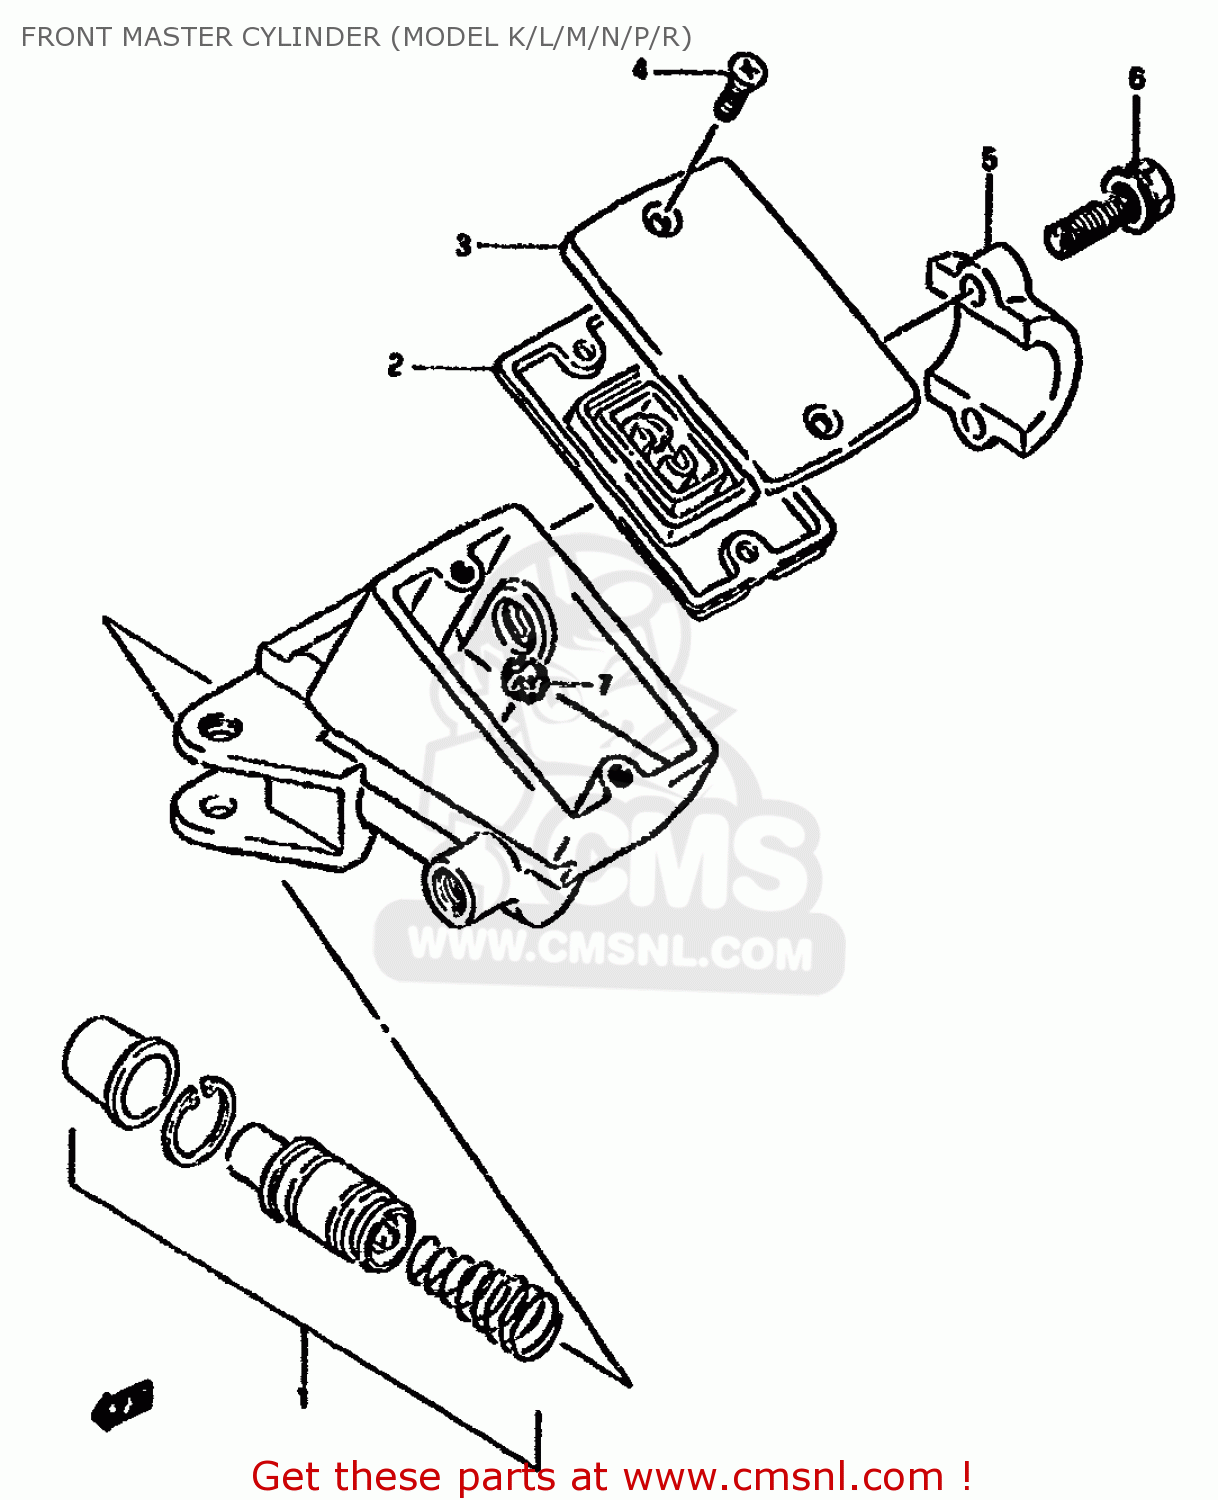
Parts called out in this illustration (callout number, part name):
1	PISTON & CUP SET
2	3-1
3	CAP
4	SCREW
5	HOLDER
6	BOLT
7	PROTECTOR
8	PROTECTOR
